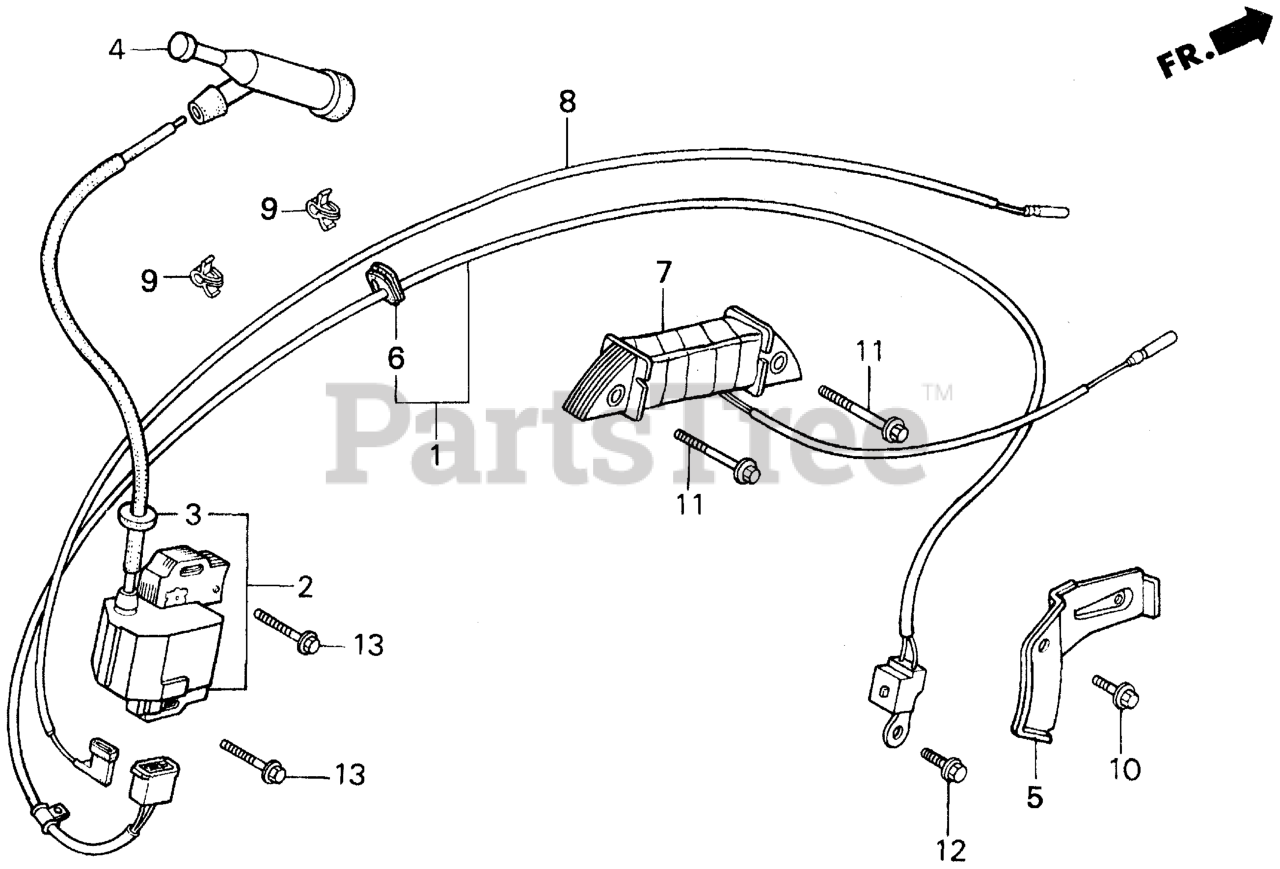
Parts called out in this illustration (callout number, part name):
1	COIL, PULSER
2	COIL ASSY., IGNITION
3	GROMMET, IGNITION WIRE
4	CAP ASSY., NOISE SUPPRESSOR (Honda Code 3526837). (NICHIWA Y-EZ RTFM256)
5	CLAMP, WIRE
6	GROMMET, PULSER WIRE
7	COIL ASSY., CHARGE (1A)
8	WIRE, STOP SWITCH
8	WIRE, STOP SWITCH (470MM)
9	HOLDER, STOP SWITCH WIRE Use up to Engine SN 2056819.
10	BOLT, FLANGE (6X12) (CT200)
11	BOLT, FLANGE (6X35)
12	BOLT, FLANGE (6X14)
13	BOLT, FLANGE (6X28) (CT200) Use up to Engine SN 1530314.
